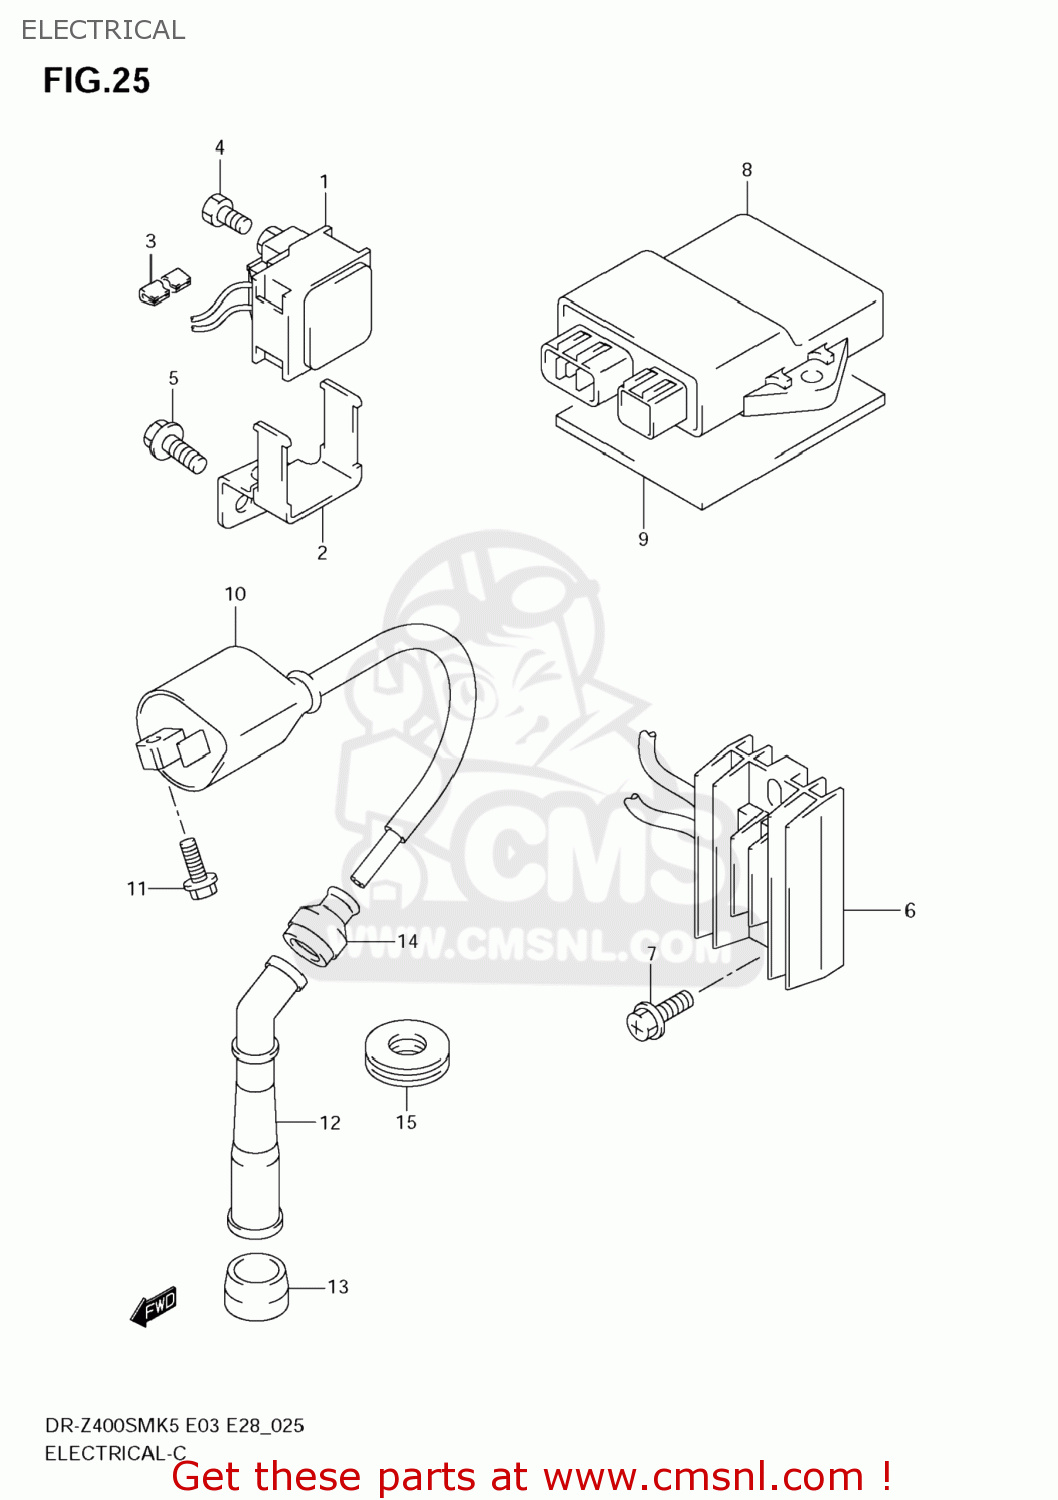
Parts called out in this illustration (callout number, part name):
1	RELAY ASSY,STARTING MOTOR
2	BRACKET,STARTING MOTOR RELAY
3	PROTECTOR,STARTING MOTOR LEAD
4	SCREW(6X8)
5	BOLT
6	RECTIFIER ASSY
7	SCREW
8	CDI UNIT
9	PROTECTOR(170X95X3.0)
10	COIL ASSY,IGNITION
11	BOLT
12	CAP,SPARK PLUG
13	SEAL,SPARK PLUG
14	SEAL,HIGH TENSION CORD
15	COVER,SPARK PLUG CAP
